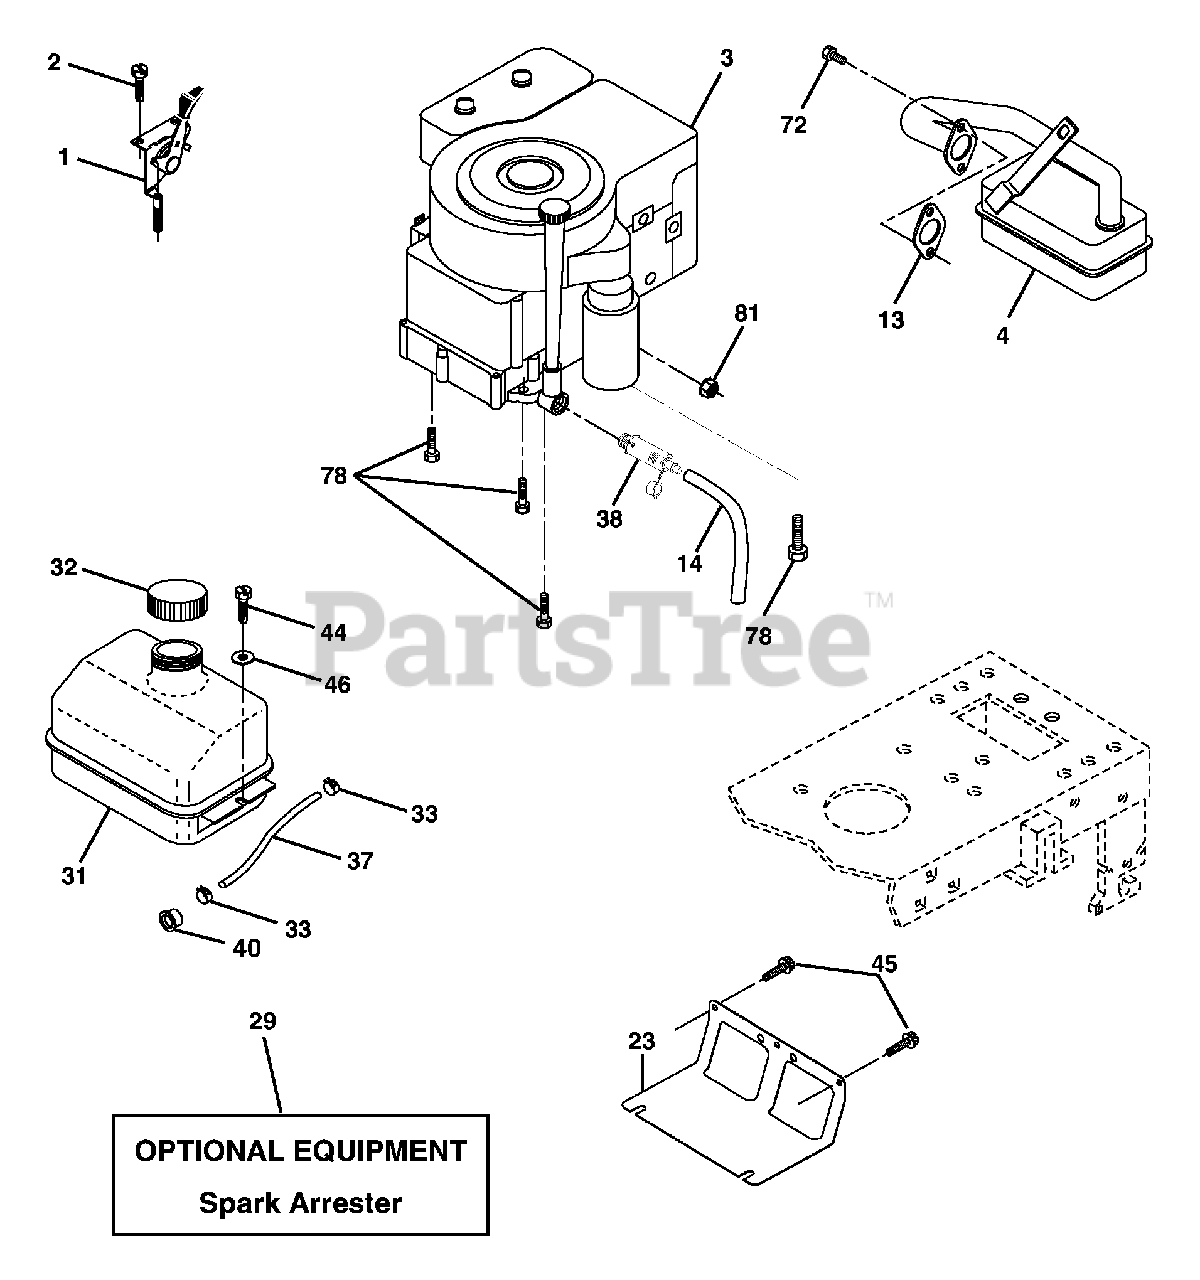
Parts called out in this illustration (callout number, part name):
1	Control Throttle/Choke Flag
2	Screw Hex Thd Cut 1/4-20 x 1/2
4	Muffler Exhaust B&S
13	Gasket Eng 1 313 Id Tin Plated
14	Tube Drain Oil Easy
23	Shield BRN/DBR Guard
29	Kit Spark Arrestor (Flat Scrn)
31	Tank Fuel Front
32	Cap Asm Fuel
33	Clamp Hose
37	Line Fuel 20"
38	Plug Drain Oil
40	Bushing Snap Nyl Blk Fuel Line
44	Screw Thdrol 1/4-20 x 3/4
45	Screw Hex Wsh Thdrol 3/8-16
46	Washer 9/32 x 7/8 x 16 Ga.
72	Screw Socket Head 5/16-18 x 1
78	Screw 3/8-16 x 1-1/4
81	Nut Keps Hex 1/4-20 unc
